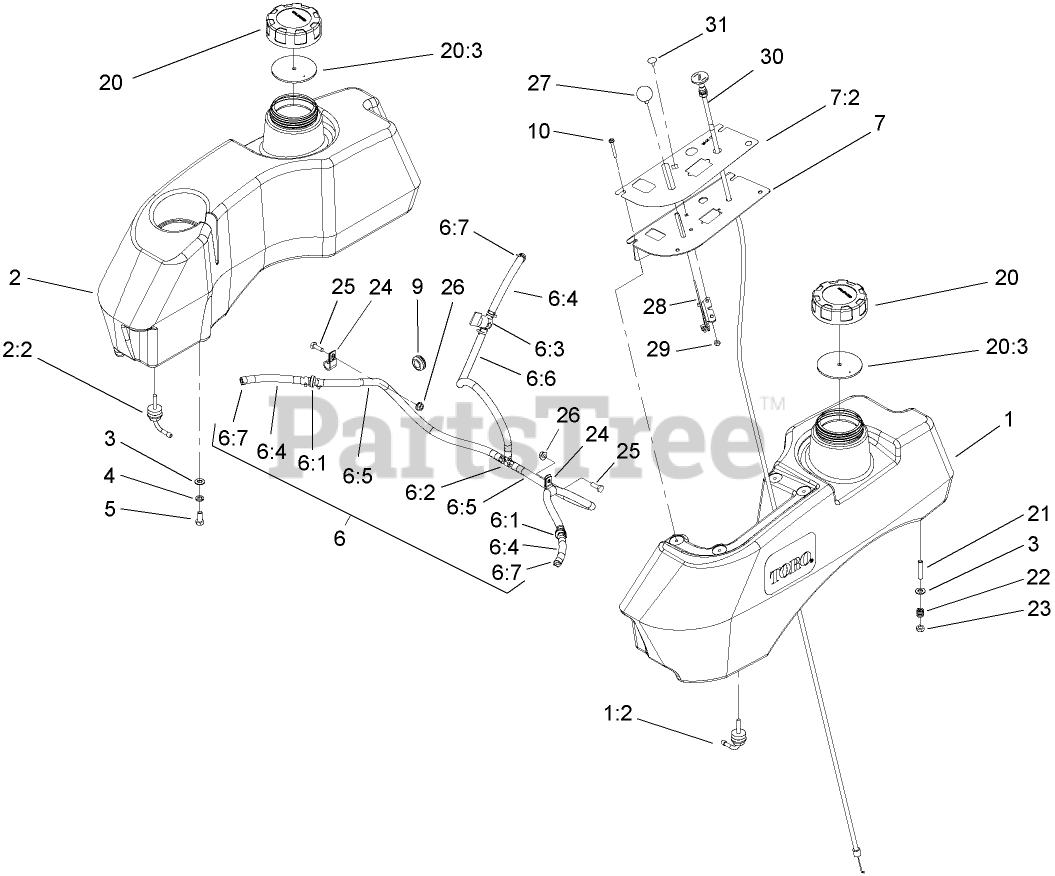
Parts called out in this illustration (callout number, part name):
1	LH FUEL TANK ASM
1:2	FITTING-FUEL, BULKHEAD
2	RH Fuel Tank ASM
2:2	FITTING-FUEL, BULKHEAD
3	WASHER-PLAIN
4	WASHER-LOCK
5	SCREW-HH
6	FUEL LINE ASM
6:1	VALVE-CHECK, FUEL
6:2	FITTING-TEE, BARBED
6:3	VALVE-FUEL
6:4	HOSE-FUEL
6:5	HOSE-FUEL
6:6	HOSE-FUEL
7	CONTROL PANEL ASM
7:2	DECAL-PANEL, CONTROL
9	GROMMET
10	SCREW-PTH
20	GAS CAP ASM
20:3	GASKET-CAP, GAS
22	SPRING-TANK, FUEL
23	NUT-LOCK, NI
24	CLIP-LOOM
25	SCREW-HH
26	NUT-HF
27	KNOB-BALL
28	THROTTLE CABLE ASM
29	NUT-LOCK, NI
30	CONTROL-CHOKE
31	BOLT-CARR
